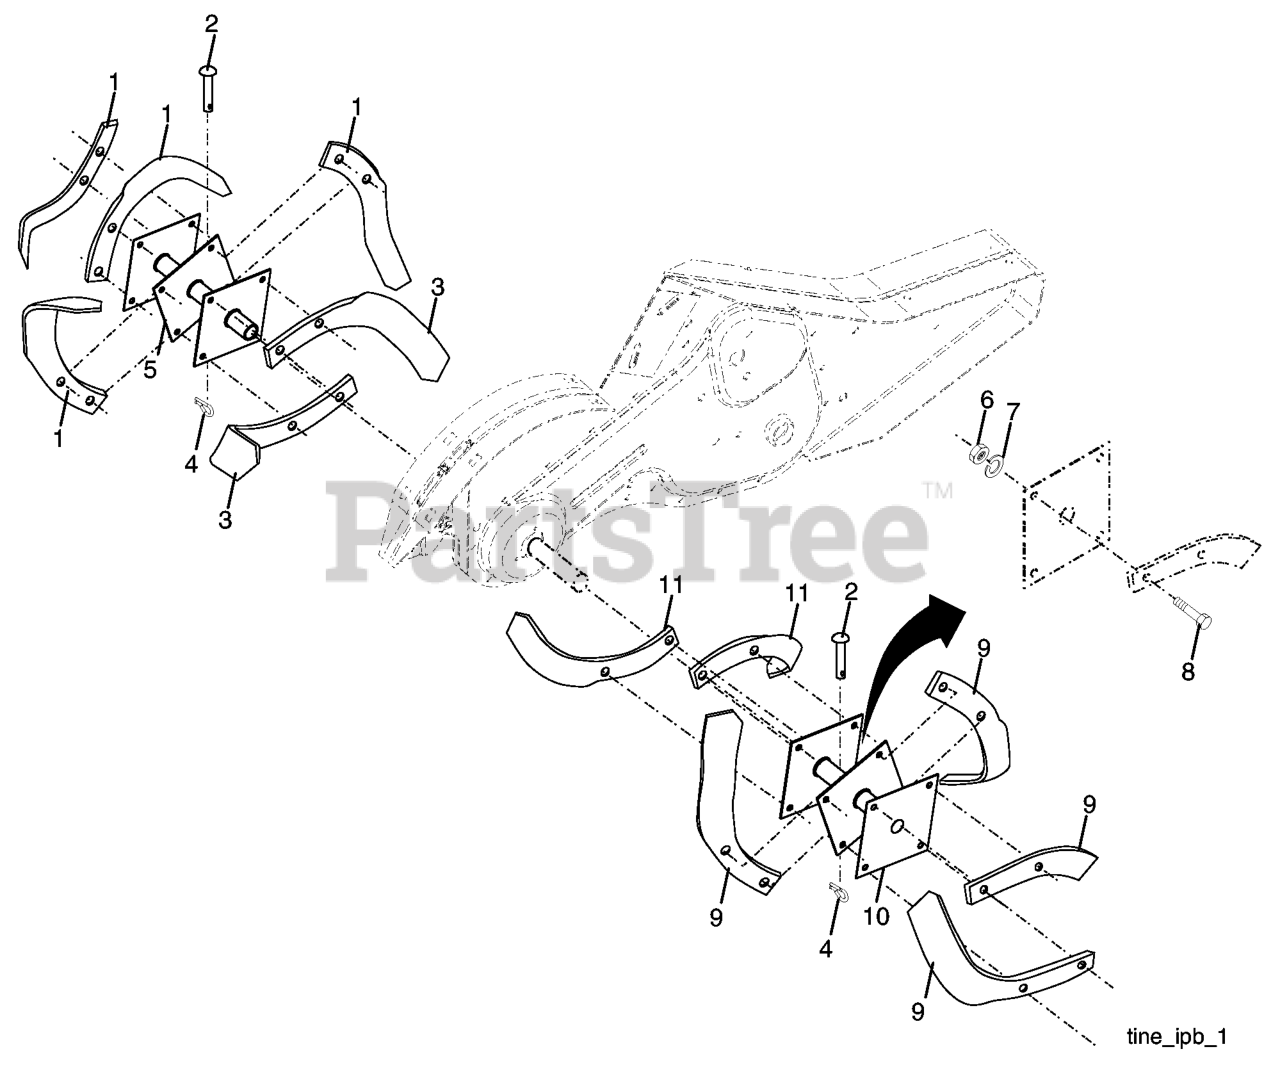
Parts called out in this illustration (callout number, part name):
1	TINE TI
2	PIN RETAINING SCREW
3	TINE.LH.12"(72L)
4	SPRING RETAINER
5	HUB.&.PLATE.ASM.LH
6	NUT
7	WASHER, LOCK 3/8
8	BOLT.HEX.001X20.37-24X1.ZINC
9	TINE TI
10	HUB & PLATE ASM RH
11	TINE.RH.12"(72R)
